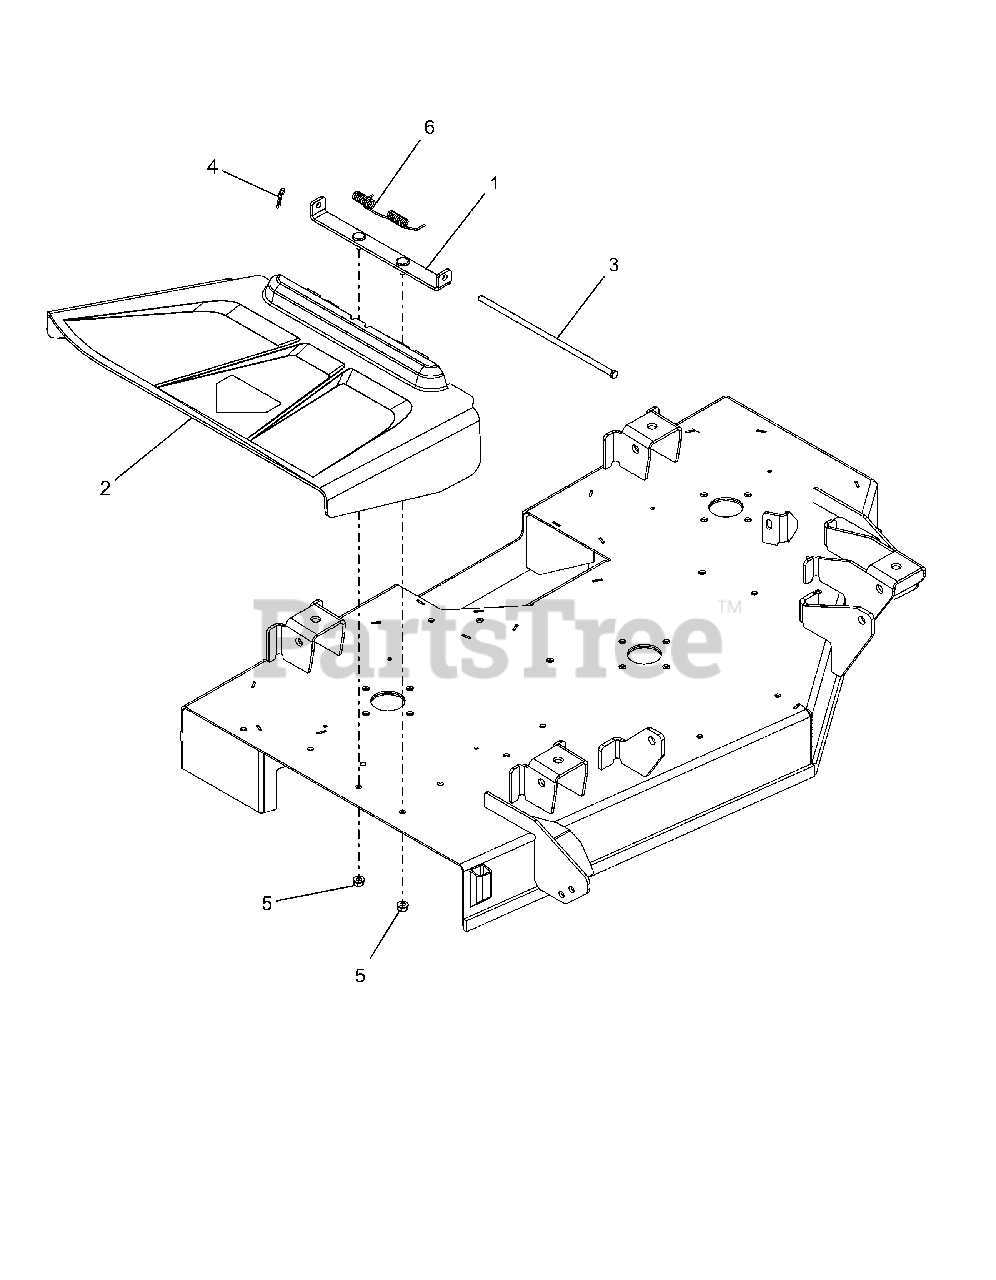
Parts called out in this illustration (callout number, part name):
1	WLDMT, CHUTE MT BRKT
2	CHUTE, SIDE DISCHARGE
3	PIN, 5/16 X 10.5
4	PIN, HAIR #213 .08X1.19 ZCC
5	NUT-LK-TOP-FLG .312-18 GF ZCC
6	SPRING-TORSION
